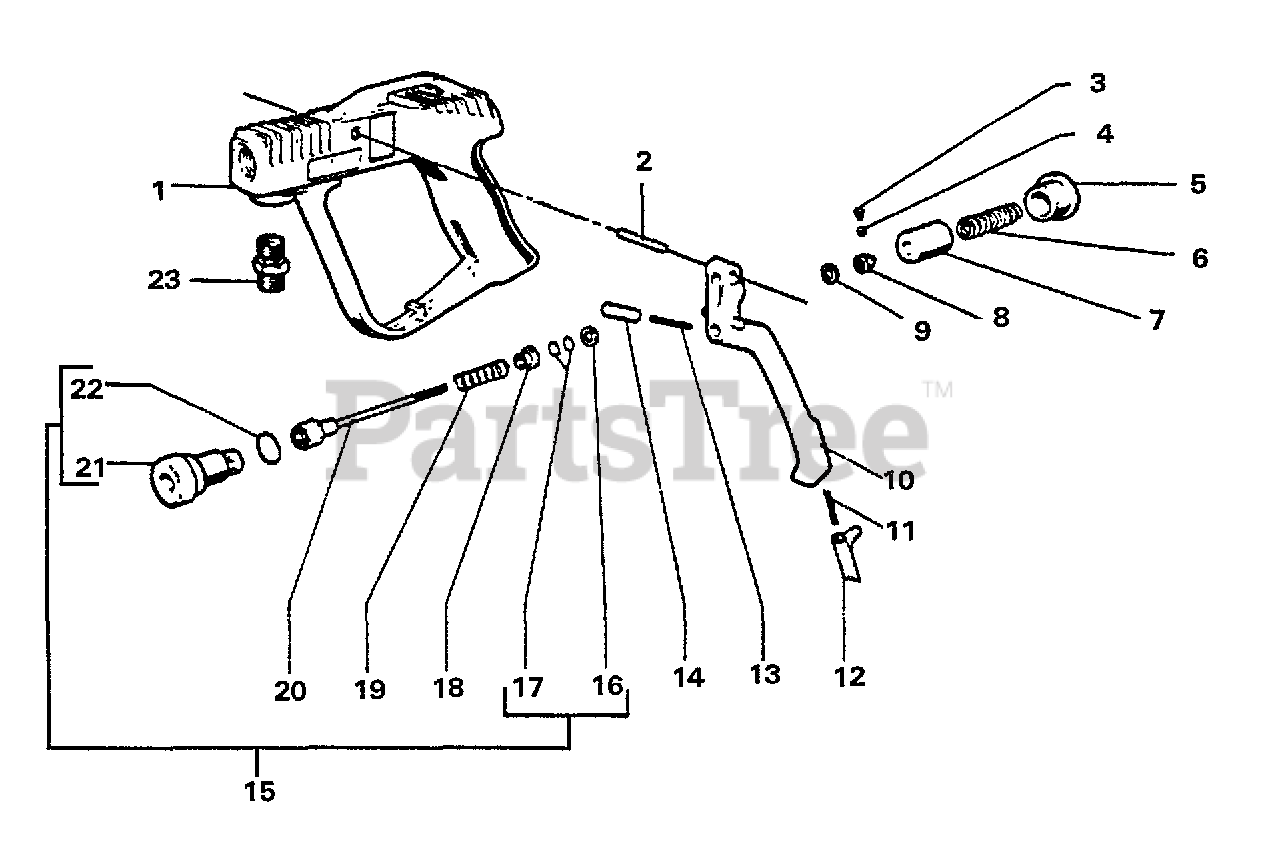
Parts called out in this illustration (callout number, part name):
1	GRIP, BODY
2	PIN, CYLINDER
3	SPRING
4	BALL, CHECK
5	CAP
6	SPRING
7	GUIDE, SPRING
8	NUT, RING
9	NUT - 4
10	LEVER, COMMAND
11	SPRING
12	LOCK PIN, SAFETY CATCH
13	SPRING
14	SHAFT
15	KIT, GRIP CONTROL VALVE
16	RING
17	O-RING 3 63×1 78 VITON
18	GUIDE, SPRING
19	SPRING
20	SHUTTER ROD ASSY
21	SEAT, VALVE
23	COUPLER
